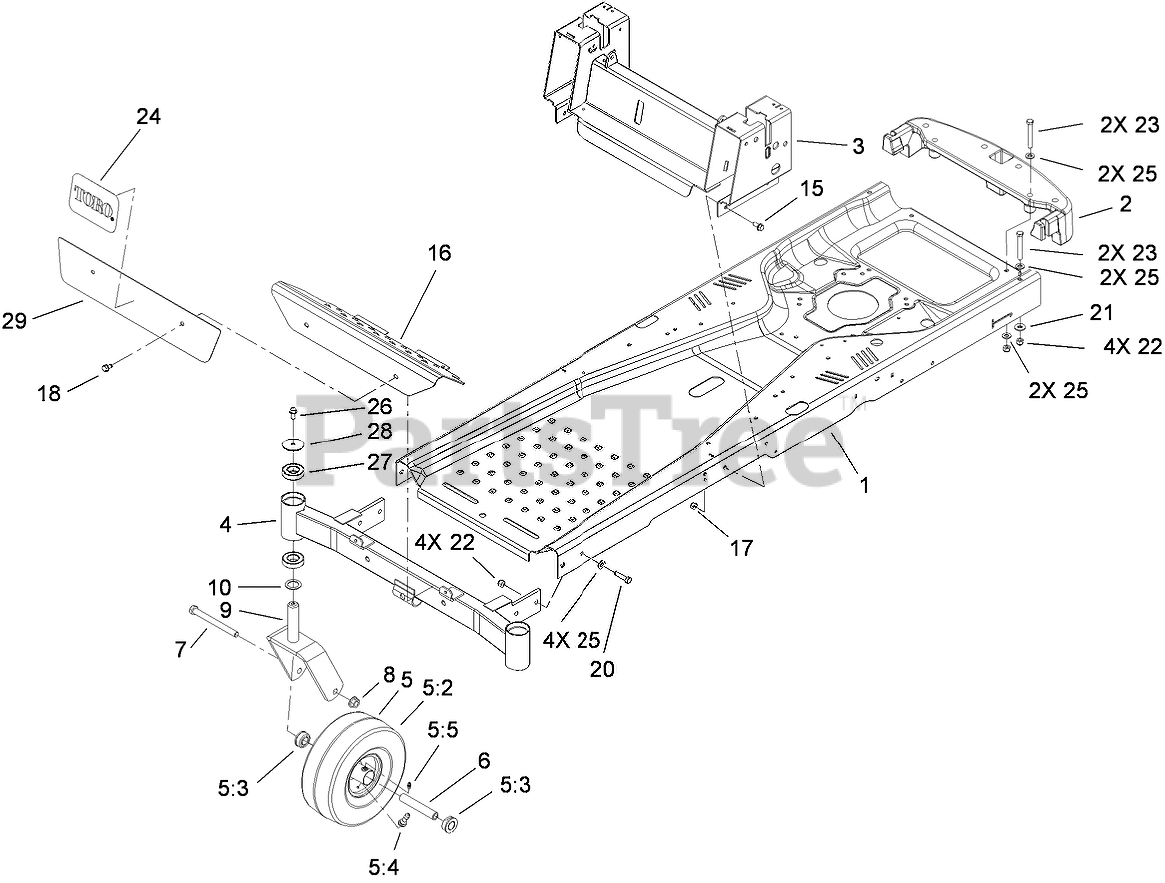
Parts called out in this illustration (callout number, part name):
2	BUMPER-REAR
3	SEAT PIVOT/CONTROL ASM
4	FRONT AXLE ASM
5	TIRE and Wheel ASM (Kenda)
5:2	TIRE-SMOOTH
5:3	BUSHING-FLANGE
5:4	STEM-VALVE
5:5	FITTING-GREASE
6	BUSHING-SPANNER
7	SCREW-HH
8	NUT-LOCK, NI
9	CASTER FORK ASM
10	WASHER-THRUST
15	SCREW-HHF
16	FOOTREST
17	NUT-LOCK, NI
18	SCREW-HWH
20	SCREW-HH
21	WASHER-HARDENED
22	NUT-LOCK, NI
23	SCREW-HH
25	WASHER-FLAT
26	SCREW-HHF
27	BEARING-BALL
28	WASHER
29	PLATE-FOOTREST
